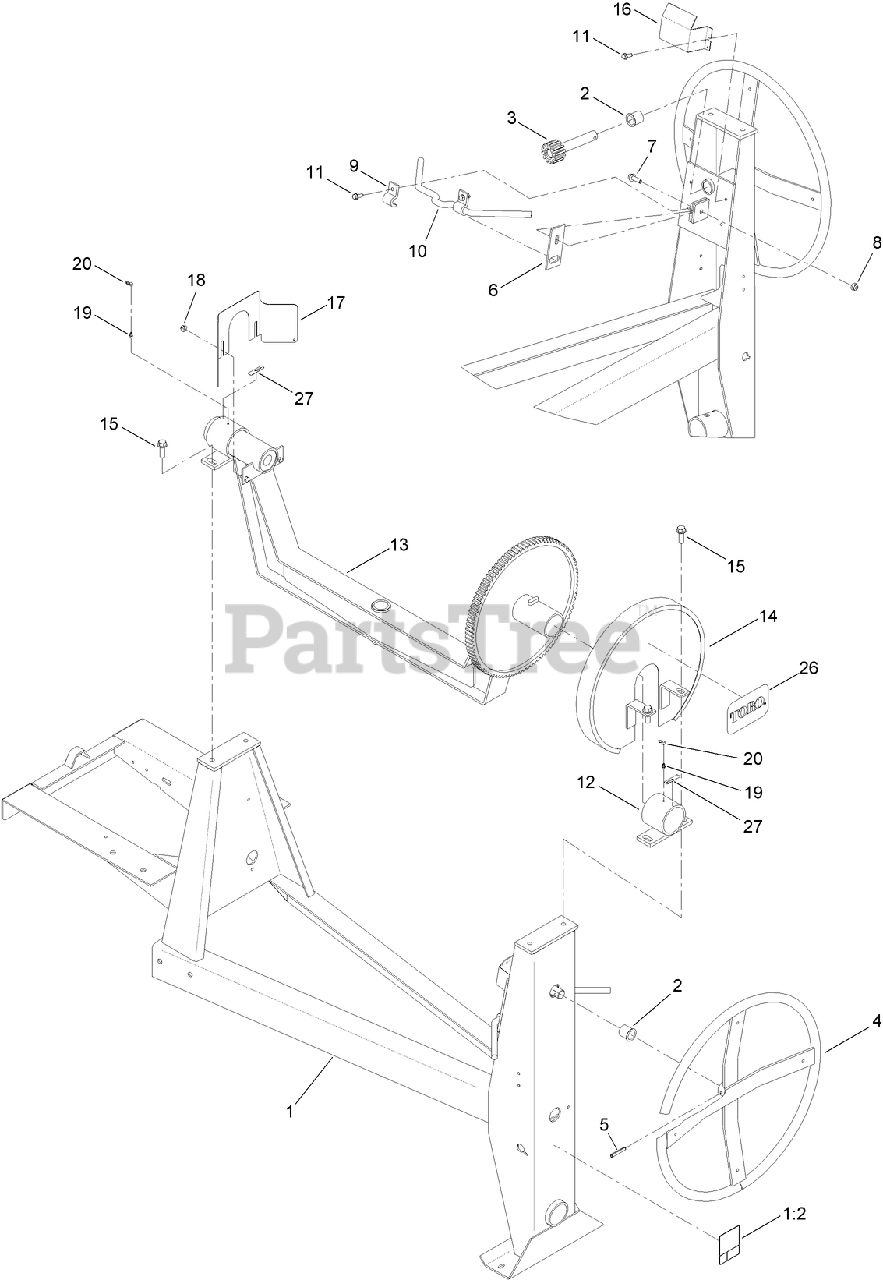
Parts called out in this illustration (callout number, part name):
1	FRAME ASM
1:2	DECAL-SAFETY CHAIN, TOWING
2	BUSHING-NYLON
3	SHAFT-TILT
4	HANDWHEEL
5	PIN-ROLL
6	DOG-BRAKE
7	SCREW-HHF
8	NUT-HF, NI
9	BRACKET-HANDLE
10	HANDLE-BRAKE
11	SCREW-HWHTF
12	TRUNNION
13	YOKE ASM
14	GUARD-BRAKE, UPPER
15	SCREW-HWH
16	GUARD-BRAKE, LOWER
17	GUARD-PINION
18	NUT-HF, NI
19	FITTING-GREASE
20	CAP-PLUG
26	DECAL
27	DECAL-GREASE
